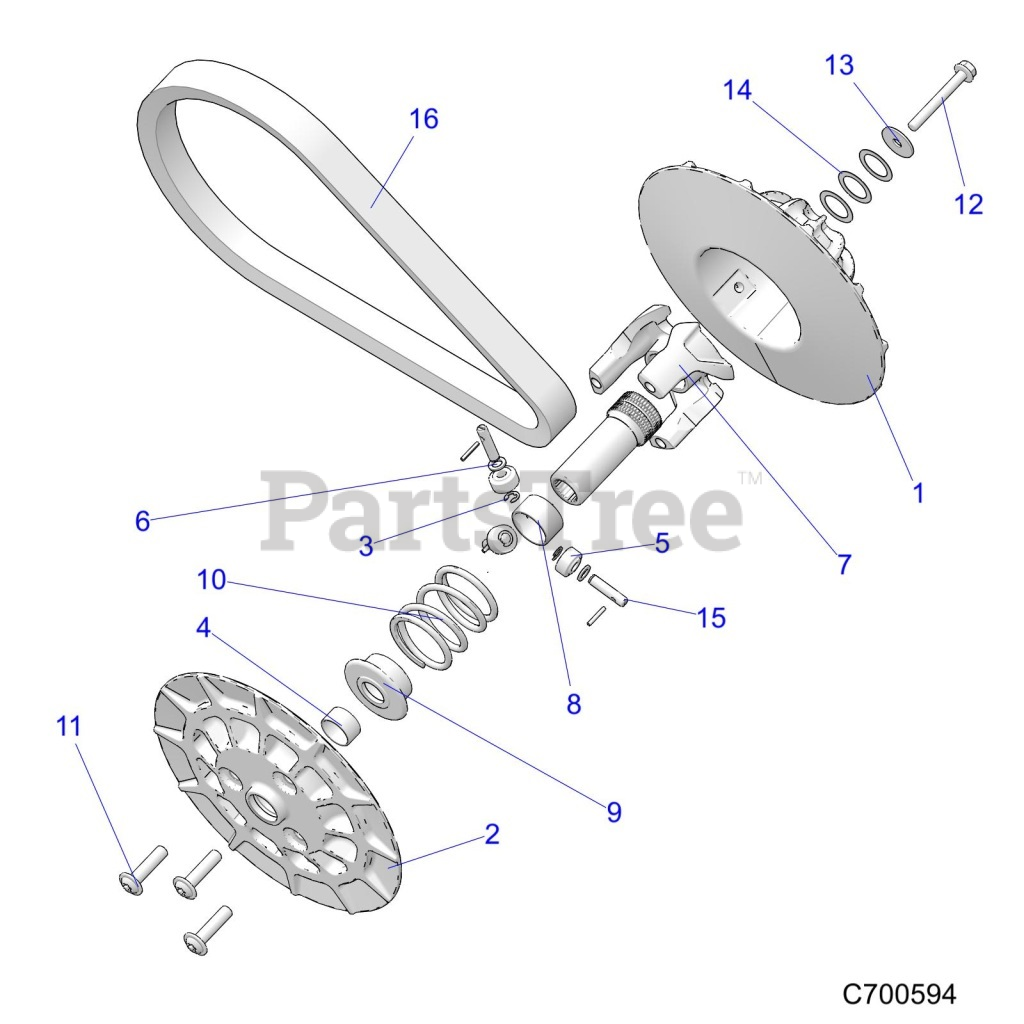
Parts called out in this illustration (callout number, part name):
1	ASM-DRIVEN,STATIONARY,P190X
2	ASM-DRIVEN,MOVEABLE,P190X,CS
2	ASM-MOVABLE SHEAVE,P190X,CS
3	E-CLIP,M6, DIN 6799
4	BEARING-DU,25X15
5	ROLLER-8X22X11.25,PA46 TW341R
6	WSHR-8.4X14 .0X1.6
7	ASM-HELIX,P190X,36-48/67BA
8	BEARING-DU,32X20
9	CUP-DRIVEN SPRING,P190X
10	SPRING,DRIVEN
11	SCR-TXFLBH-M10X1.25X40 10.9SPC
12	SCR-M8X1.25X65-HX/FL-Y,CL 10.9
13	WSHR-8.4X30. 0X2.0 ZPB
14	SHIM-RING,23.25X32.25X0.5
15	PIN-DRIVEN,ROLLER,8MM
16	BELT-DRIVE
